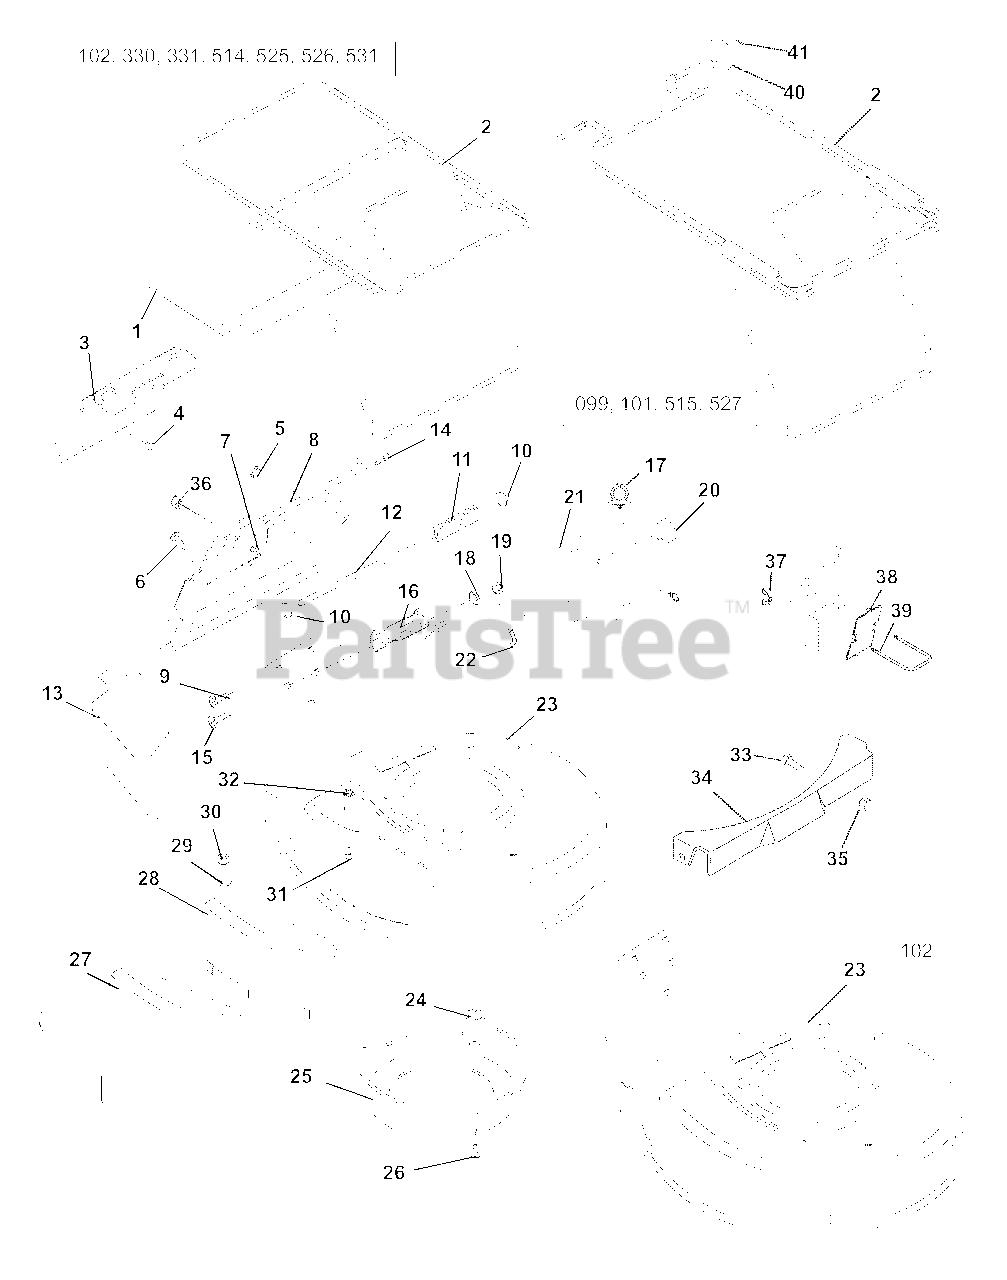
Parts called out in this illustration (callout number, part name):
1	BAG, CONSUMER BLACK 15 OZ/YD2
1	BAG, BAG-N-DRAG
2	FRAME, BAGGER
2	FRAME, BAG-N-DRAG
3	CATCHER PLATE DOOR
4	BUTTON BUMPER
6	@SCR-TAP 12-24X.50 HWH TR YWZC
7	SCR-TAP 10-24X.375 TORX PHD YZ
8	CATCHER PLATE
8	PLATE, CATCHER
9	@BLT-RHDSSQNK .25-20X.38 G2YZ
10	PUSH NUT, .25
11	SG-TORS .120X.68X3.09
12	DOOR PIN
13	MULCH MASTER MULCHER ACCESSORY
14	@NUT-SPNLK-FLG .25-20 YWZC
15	@BLT-RDHDSQNK .25-20X.75 G5YZ
16	HINGE BASE WELDMENT
16	HINGE PLATE WELDMENT
17	SNAP-IN CLIP
18	WSHR-LK .250X.077 HVY YWZC
19	@NUT-HEX .25-20 YWZC
20	WING - NUT
21	COVER, DRIVE
22	TRIM BUMPER
23	MOWER PAN HEAD W/SFTYDECALS SP
23	MOWER PAN W/DECALS SP/COM
23	MOWER PAN W/ SFTY DCLS SP BBC
24	PLASTIC GROMMET
25	CENTER BAFFLE
26	SCR-TAP 10-16X.62 SLPH AB YWZC
27	SIDE DISCHARGE ASSEMBLY
28	COVER, SIDE DISCHARGE
29	@WSHR-FL-STL.406X.812X.065 YWZ
30	@NUT-LK-NYL .312-18 YWZC
31	BLT-RDHDSQSHK.31-18X.75 GR2 YW
32	NUT-PUSH .312
33	@BLT-RDHDSQNK .31-18X.50 G5YZ
34	PANEL-FRONT
35	@NUT-LK-CTR .31-18 YWZC
35	@NUT-SPNLK-FLG .312-18 YWZC
36	@NUT-SPNLK-FLG .25-20 YWZC
37	NUT-WING #8-32 YWZC
38	BATTERY PLATE
39	U-BOLT
41	CAP, 3/8 ROD YWZC
